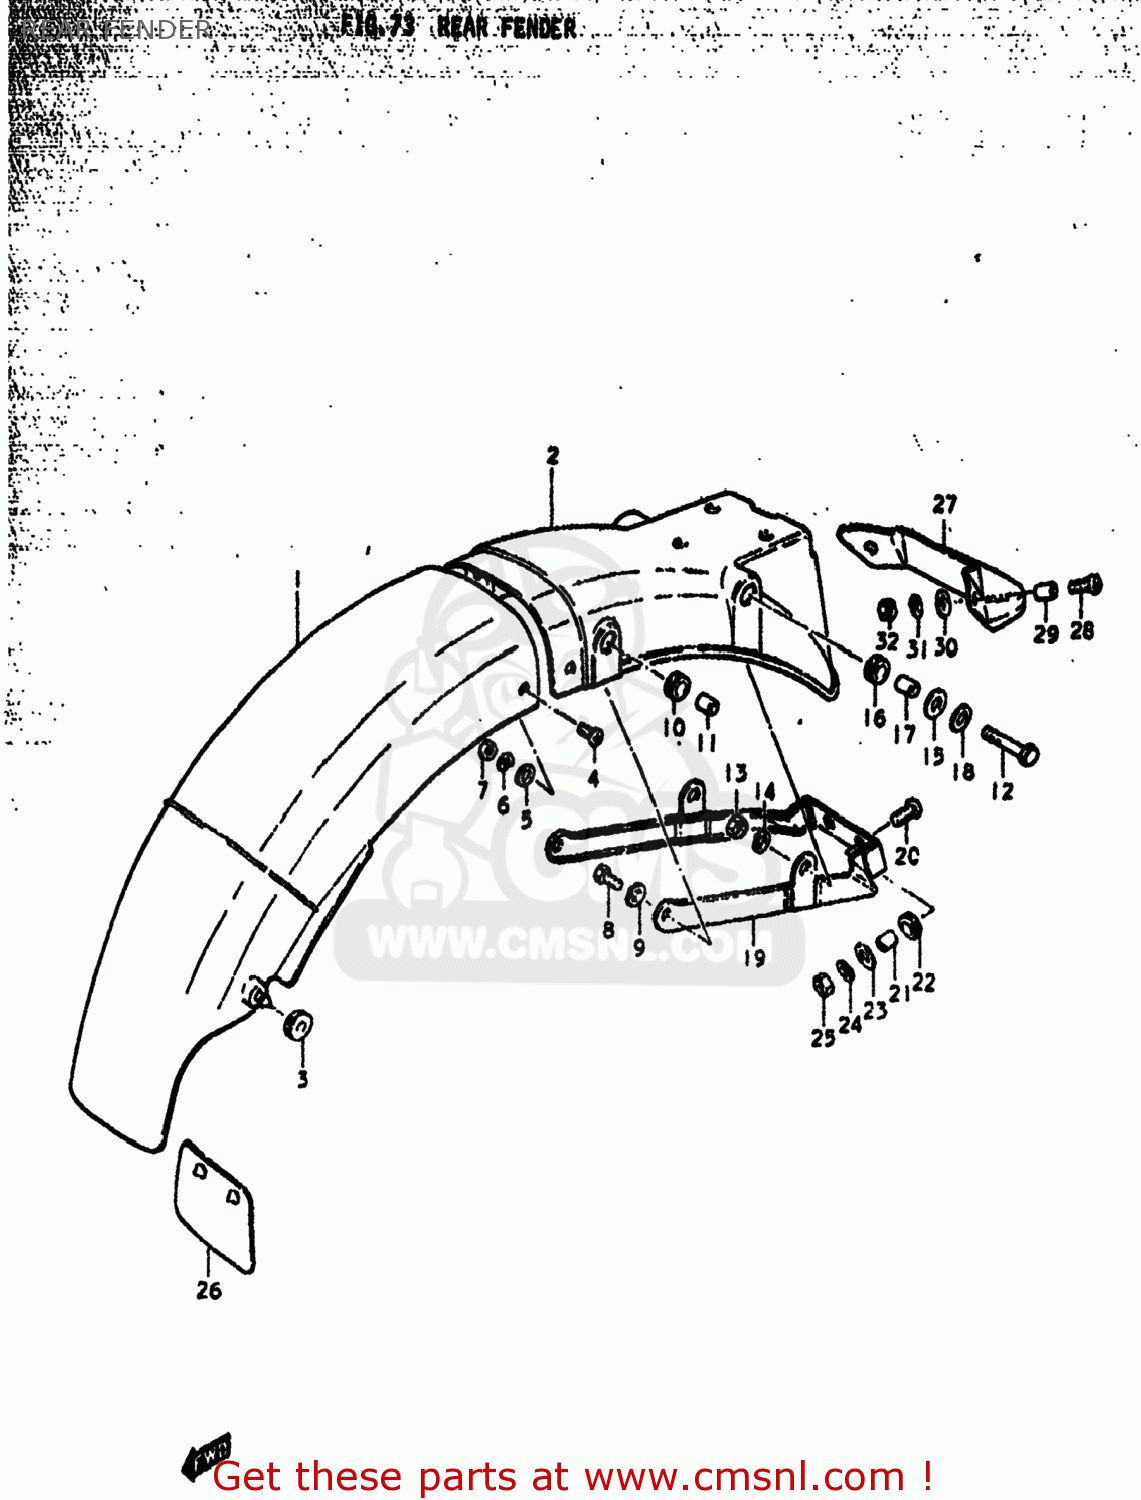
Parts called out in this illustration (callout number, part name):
1	FENDER,REAR
2	FENDER,REAR
3	CUSHION
4	SCREW
5	WASHER (5.5X16X1.2)
6	LOCK WASHER
7	NUT
8	BOLT
9	LOCK WASHER
10	CUSHION
11	SPACER(6.1X9X7.5)
12	BOLT
13	NUT
14	LOCK WASHER
15	WASHER(8.5X26X1.2)
16	CUSHION
17	SPACER (8.2X12X7.5)
18	WASHER
19	REINFORCEMENT,REAR FENDER
20	SCREW
21	SPACER (6.1X9X9)
22	CUSHION
23	WASHER(6,5X22X1.6)
24	LOCK WASHER
25	NUT
26	GUIDE,RR FENDER MUD
27	EXTENSION,REAR FENDER
28	SCREW (6X15)
29	SPACER(6.2X8.3X5.7)
30	WASHER(6.5X18X1)
31	LOCK WASHER
32	NUT
